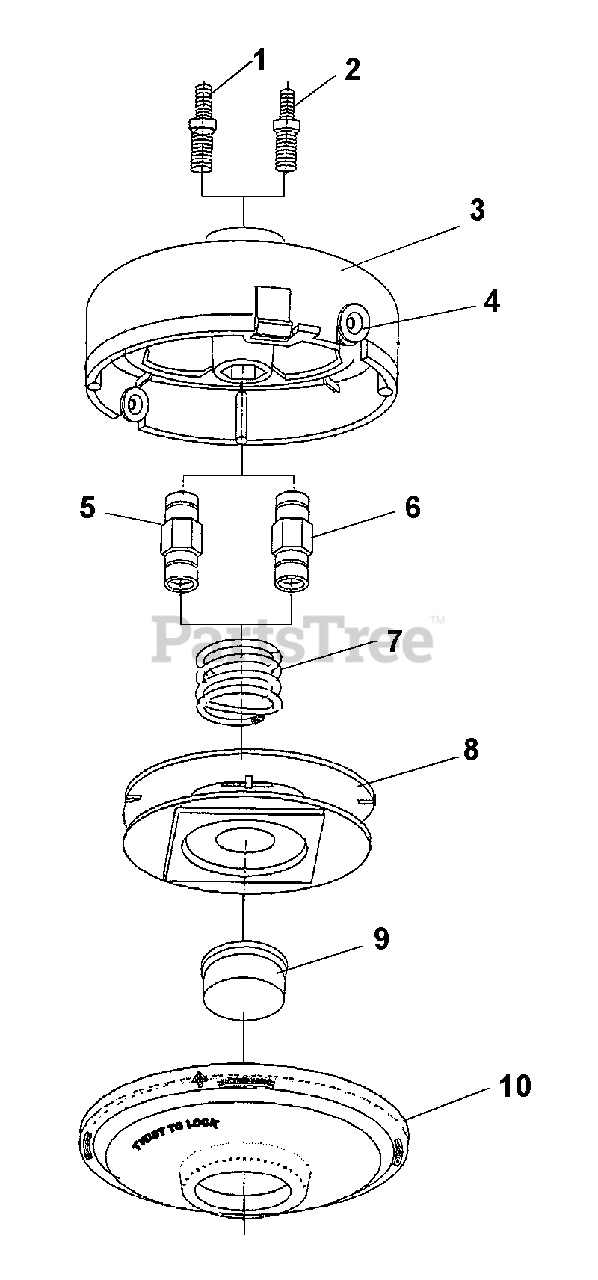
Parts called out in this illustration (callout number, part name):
1	STUD, SHAFT BOLT - 8X10
2	STUD, SHAFT BOLT - 7X10
3	HOUSING
4	EYELET
5	SHAFT, BOLT 10 X 1.25 FLH X 8 X 1.25 FLH
6	SHAFT, BOLT 10 X 1.0 FLH X 3/8 X 24 FLH
7	SPRING
8	SPOOL W/O LINE
9	BUTTON
10	COVER
